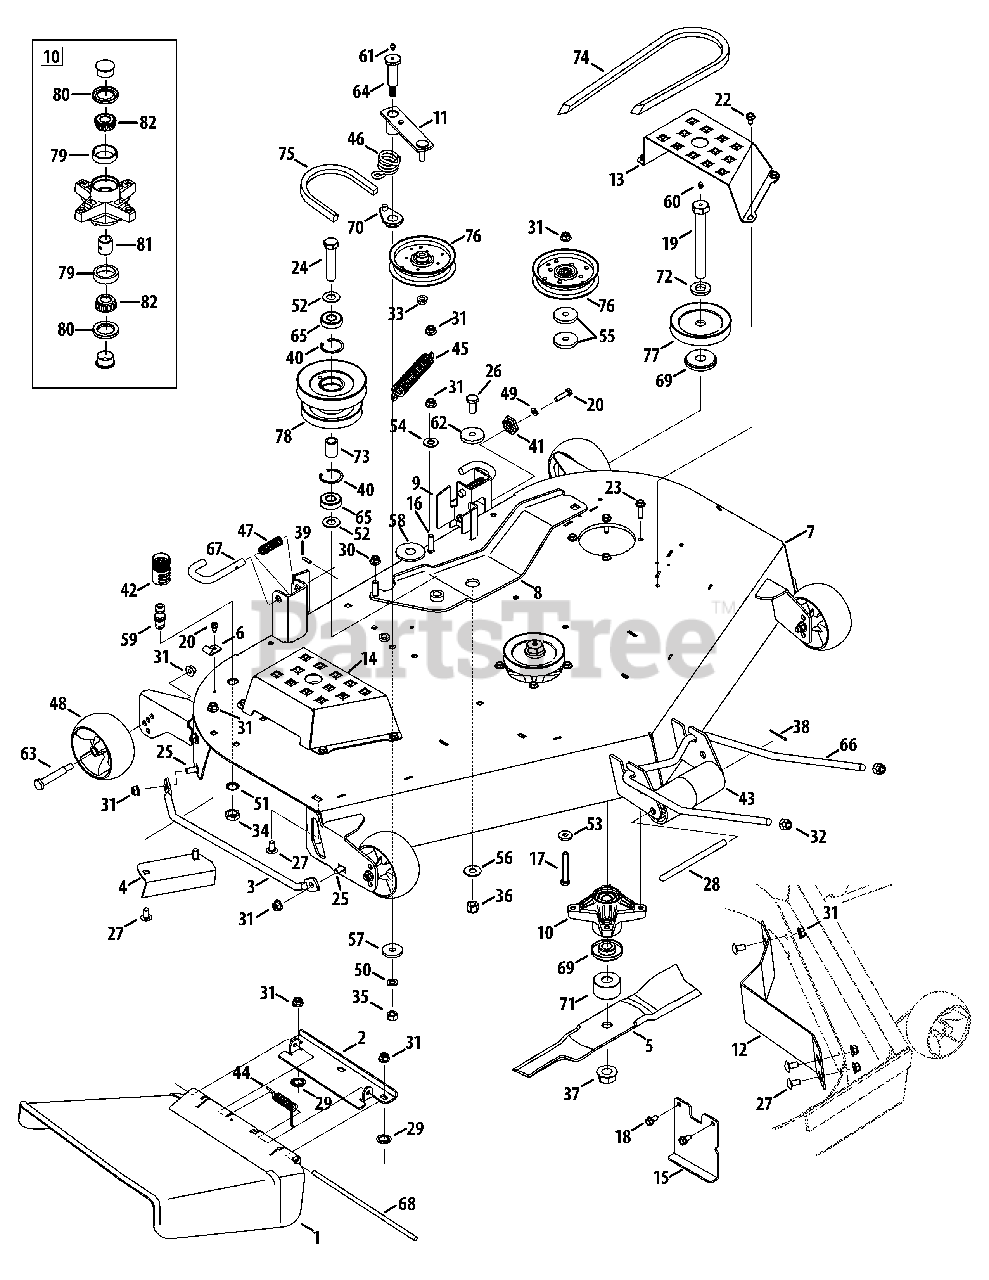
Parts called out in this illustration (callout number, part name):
1	Chute Deflector
2	Chute Bracket
3	Finger Guard
4	Micro Chute Baffle
5	Blade, 17
6	Hook Retainer Bracket
7	Deck Assembly
8	PTO Idler Assembly
9	Hanger Adjustment Bracket
10	Spindle Assembly
11	Idler Arm
15	Up-Stop Bracket
16	Carriage Bolt, 3/8 x 16 x 1.50
17	Hex Screw, 3/8-16 x 2.50
18	Hex Washer, 5/16-18 x .750
19	Hex Screw, 3/4-16 x 6.00
20	Hex Screw, 5/16-18 x 1.25
21	Hex Washer Screw, 1/4-20 x .500
22	Hex Washer Screw, 5/16-18 x .625
23	Hex Washer Screw, 5/16-18 x 1.250
24	Hex Screw, 5/8-18 x 3.00
25	Carriage Bolt, 3/8-16 x 1.00
26	Hex Screw, 1/2-20 x 1.50
27	Carriage Bolt, 3/8-16 x .75
28	Roller Pin, 1/2 x 7.31
29	Push Nut, 3/8
30	Flange Lock Nut, 5/16-18
31	Flange Lock Nut, 3/8-16
32	Flex Lock Nut, 1/2-13
33	Flange Lock Nut, 3/8-16
34	Hex Nut, M16-1.5
35	Hex Nut, 7/16-14
36	Hex Lock Nut, 1/2-20
37	Flange Lock Nut, 3/4-16
38	Cotter Pin, 3/32 x 1.25
39	Spirol Spring Pin
40	Retainer Ring
41	Deck Adjustment Gear
42	Water Nozzle Adapter
43	Front Roller
44	Torsion Spring, 180 x .639 x 2.16 x .12
45	Extension Spring, 1.0 x 6.140
46	Idler Torsion Spring, 1.10 x 1.3
47	Compression Spring, .66 x 1.8
48	Deck Wheel, 5.0
49	Lock Washer, 5/16
50	Lock Washer, 7/16
51	Lock Washer, 5/8
52	Flat Washer, .65 x 1.25 x .075
53	Flat Washer, .385 x 1.0 x .135
54	Flat Washer, .510 x 1.000 x .125
55	Flat Washer, .4375 x 1.75 x .25
56	Flat Washer, .531 x 1.062 x .134
57	Flat Washer, .45 x 1.5 x .172
58	Flat Washer, .535 x 1.92 x .060
59	Deck Water Nozzle
60	Grease Fitting, 1/4-28 x 3/16
61	Drive Lube Fitting, 3/16
62	Shoulder Spacer, .9790 x .2025
63	Shoulder Screw, 1/2 x 2.50
64	Shoulder Screw, 7/16-14 x .68 x 2.11
65	Ball Bearing, .625 x 40 x 12
66	Front Hanger Rod
67	Mower Support Pin
68	Chute Deflector Rod
69	Spindle Spacer
70	Spring Retainer
71	Spindle Spacer, .760 x 2.0 x 1.10
72	Spacer, .812 x .218
73	Spacer, .88 x .635 x 1.25
76	Idler Pulley
78	Double Pulley
79	Bearing Cup, .750
80	Oil Seal
81	Bearing Spacer, .78 x 1.0 x 1.0425
82	Cone Bearing, .750
